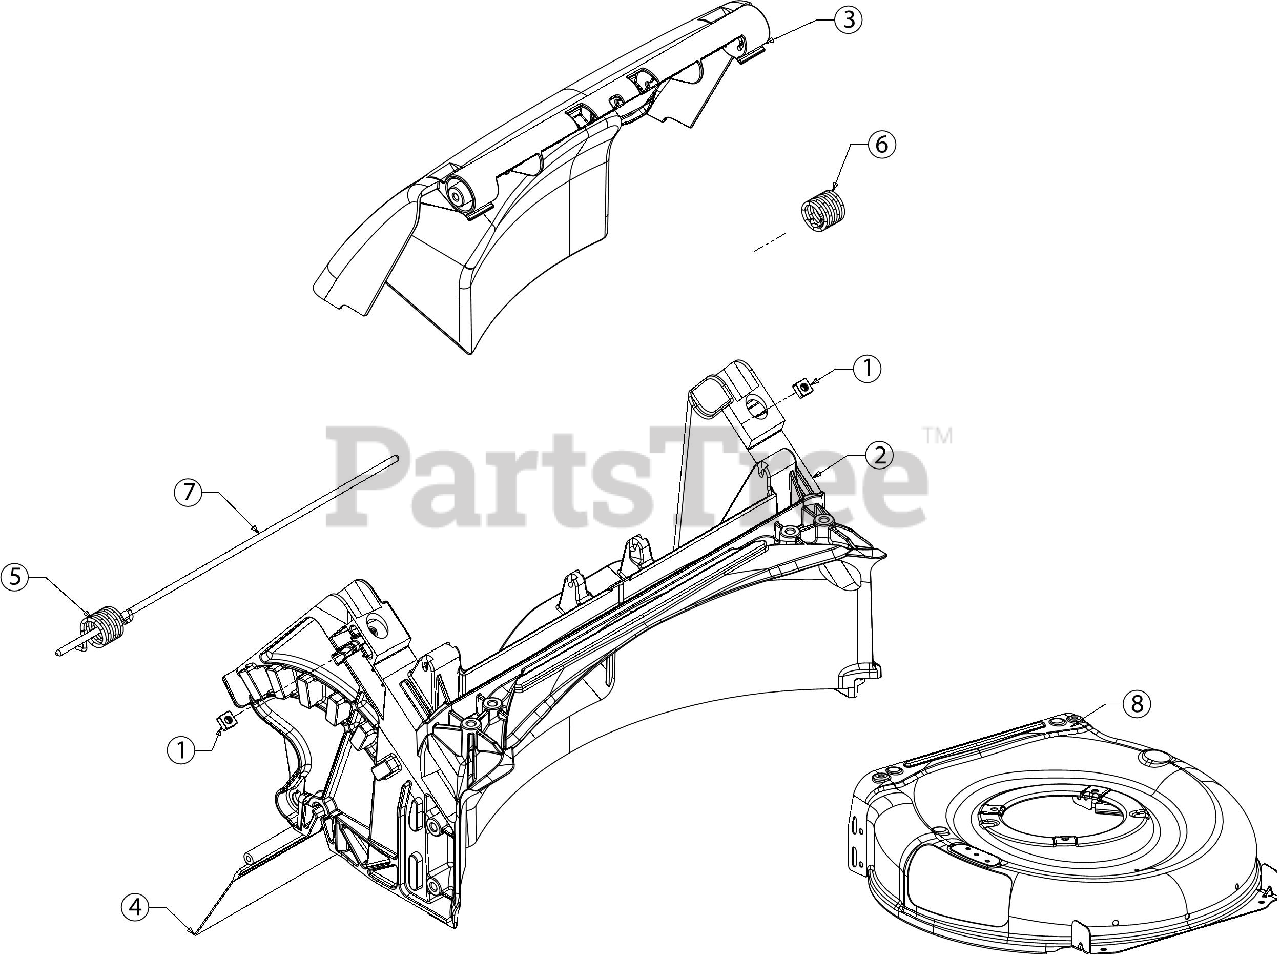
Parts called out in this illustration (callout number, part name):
1	SQUARE NUT 1/4-20
2	DOOR ASSEMBLY
3	REAR MULCH COVER
4	TRAILSHIELD
5	TORSION SPRING (RH)
6	TORSION SPRING (LH)
7	REAR DOOR PIVOT ROD
8	21" DECK (3N1)
